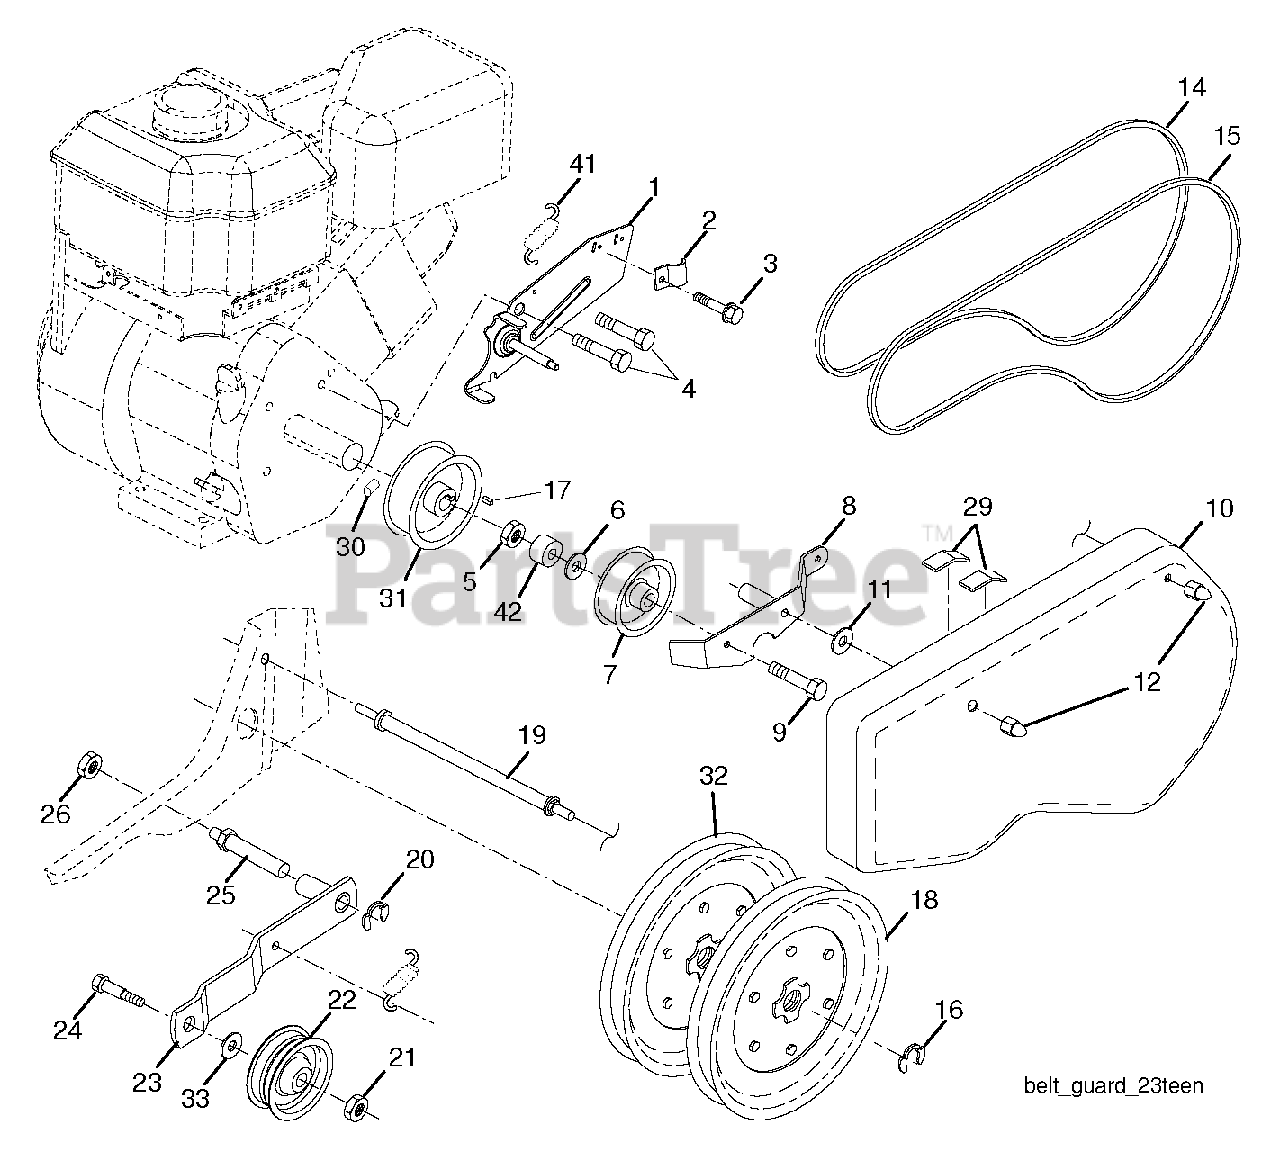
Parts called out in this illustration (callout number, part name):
1	RP ASSEMBLY,BRACKET,BELTGUARD
2	CLIP.PLATED
3	SCREW.HXTAP.10-24
5	NUT.LOCK.5/16-18
6	BUSHING SPACER.AXLE
7	PULLEY FLAT IDLER
8	ARM.ASM.REV.IDLER.TILLER.BLACK
9	BOLT.FIN HEX 5/16-18UNC X2 1/4
10	GUARD.BELT.TILLER.ORANGE
12	CAP
15	BELT.TILLER.DRIVE
16	RETAINING RING LT
17	KEY.SQ.187 X 1.125
18	SHEAVE,TRANS."D"
19	BOLT.BELT.GUARD
20	KLIP RING TI
21	NUT.LOCK.5/16-18
22	PULLEY.W/SPACER.2.25
23	ARM.ASM.IDLER.PNT
24	HEX BOLT
25	SHAFT.IDLER.TILLER
26	JAM NUT TI
29	PAD IDLER TI
31	ENGINE.PULLEY.TILLER
32	SHEAVE.TRANS
33	WASHER.20X8.5
41	SPRING.EXTENSION
42	SPACER.CONTROL.LEVER
